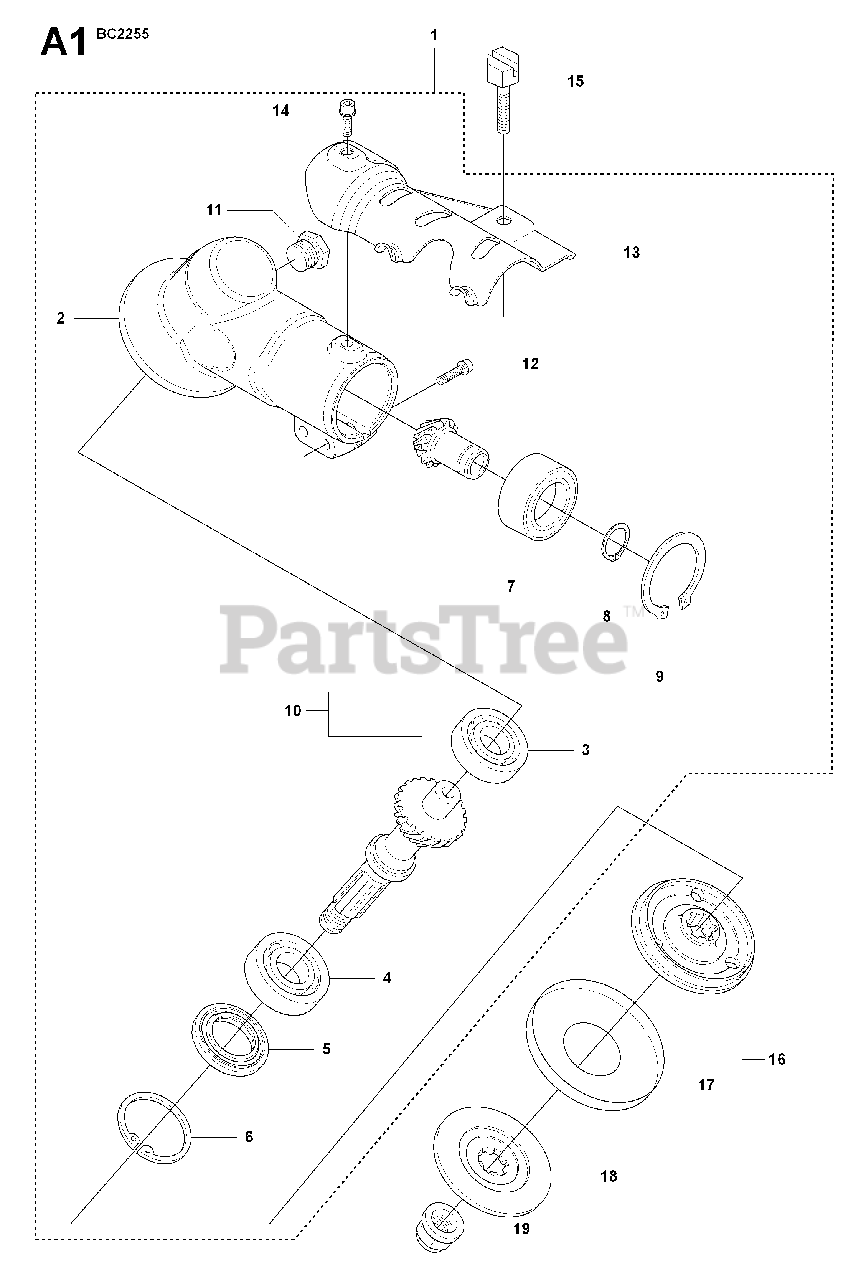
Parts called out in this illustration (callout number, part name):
1	BEVEL GEAR
2	GEAR HOUSING
3	BALL BEARING
4	BALL BEARING
6	RETAINING RING SGH 35
8	RETAINING RING SGA 15
9	RETAINING RING
10	BEVEL GEAR
13	ATTACHMENT PLATE
16	RP CARRIER
17	GRASS SEALING
18	SUPPORT FLANGE
19	BLADE NUT
